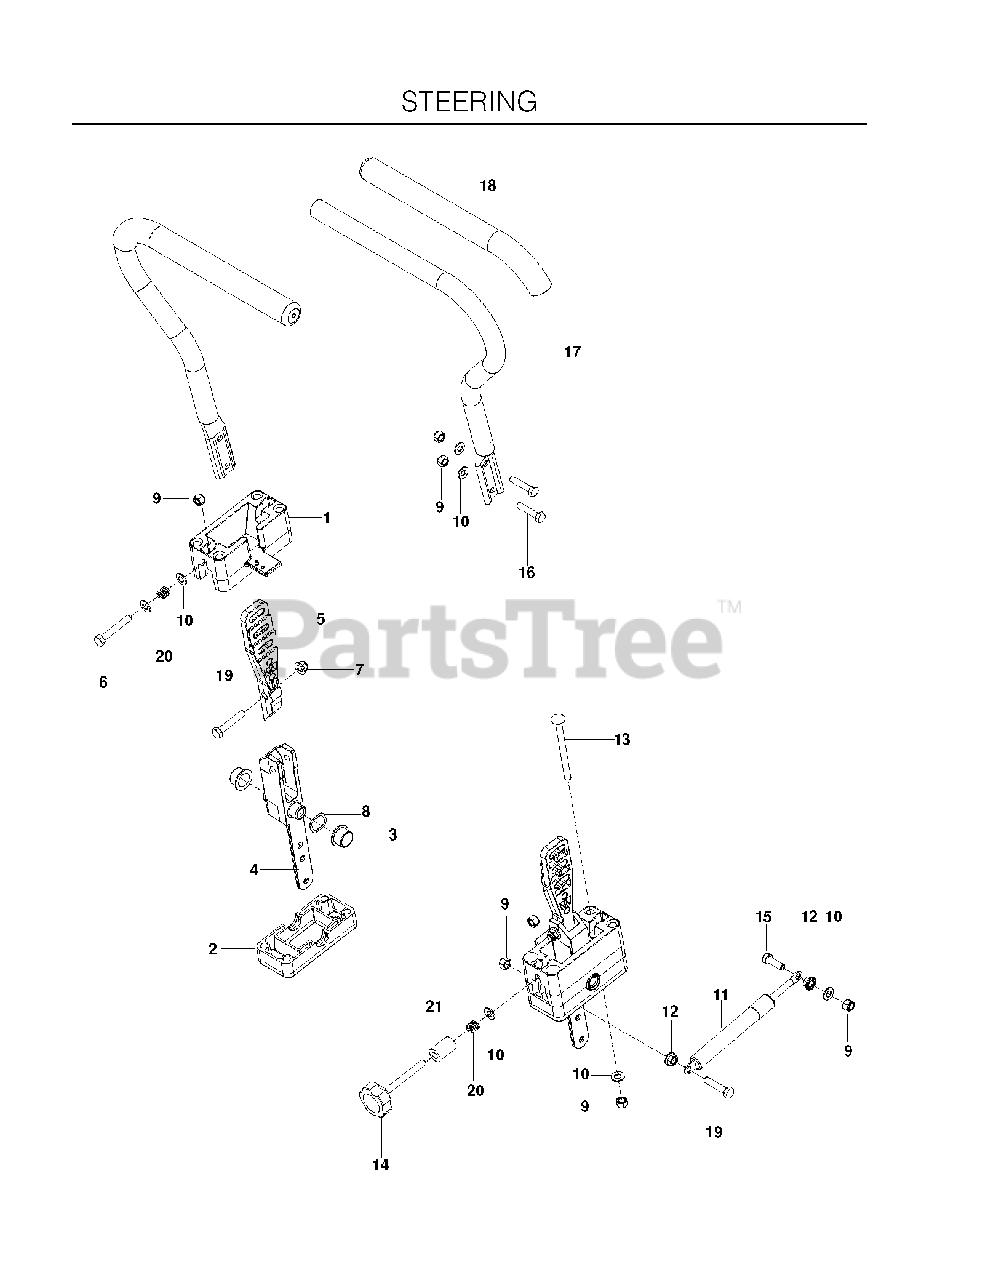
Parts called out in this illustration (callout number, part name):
1	BLOCK, UPPER
2	BLOCK, LOWER
3	BEARING, FLANGE
4	PIVOT.SECTION.DRIVE.CONTROL
5	MOUNT, DR CNTRL HANDLE
6	HCS 5/16-18 X 2 TPBLT GR 5 ZD
7	5/16-18 NYLOC FLANGE NUT
8	WASHER, .825 X 1.087, WAVE
9	NUT 5/16 NYLOC
10	FLAT WASHER 5/16 SAE
11	DAMPENER
12	NUT 5/16C WHIZ
13	RHSNB 5/16-18 X 4 GR 5 ZD
14	Knob, 3"
15	HCS 5/16C X 1
16	CAPSCREW 5/16 X 1/1/2 HEX HEAD
17	ASSEMBLY, DRIVE LEVER
18	GRIP, FOAM (GROUND) 15
19	HCS 5/16C X 1 3/4
